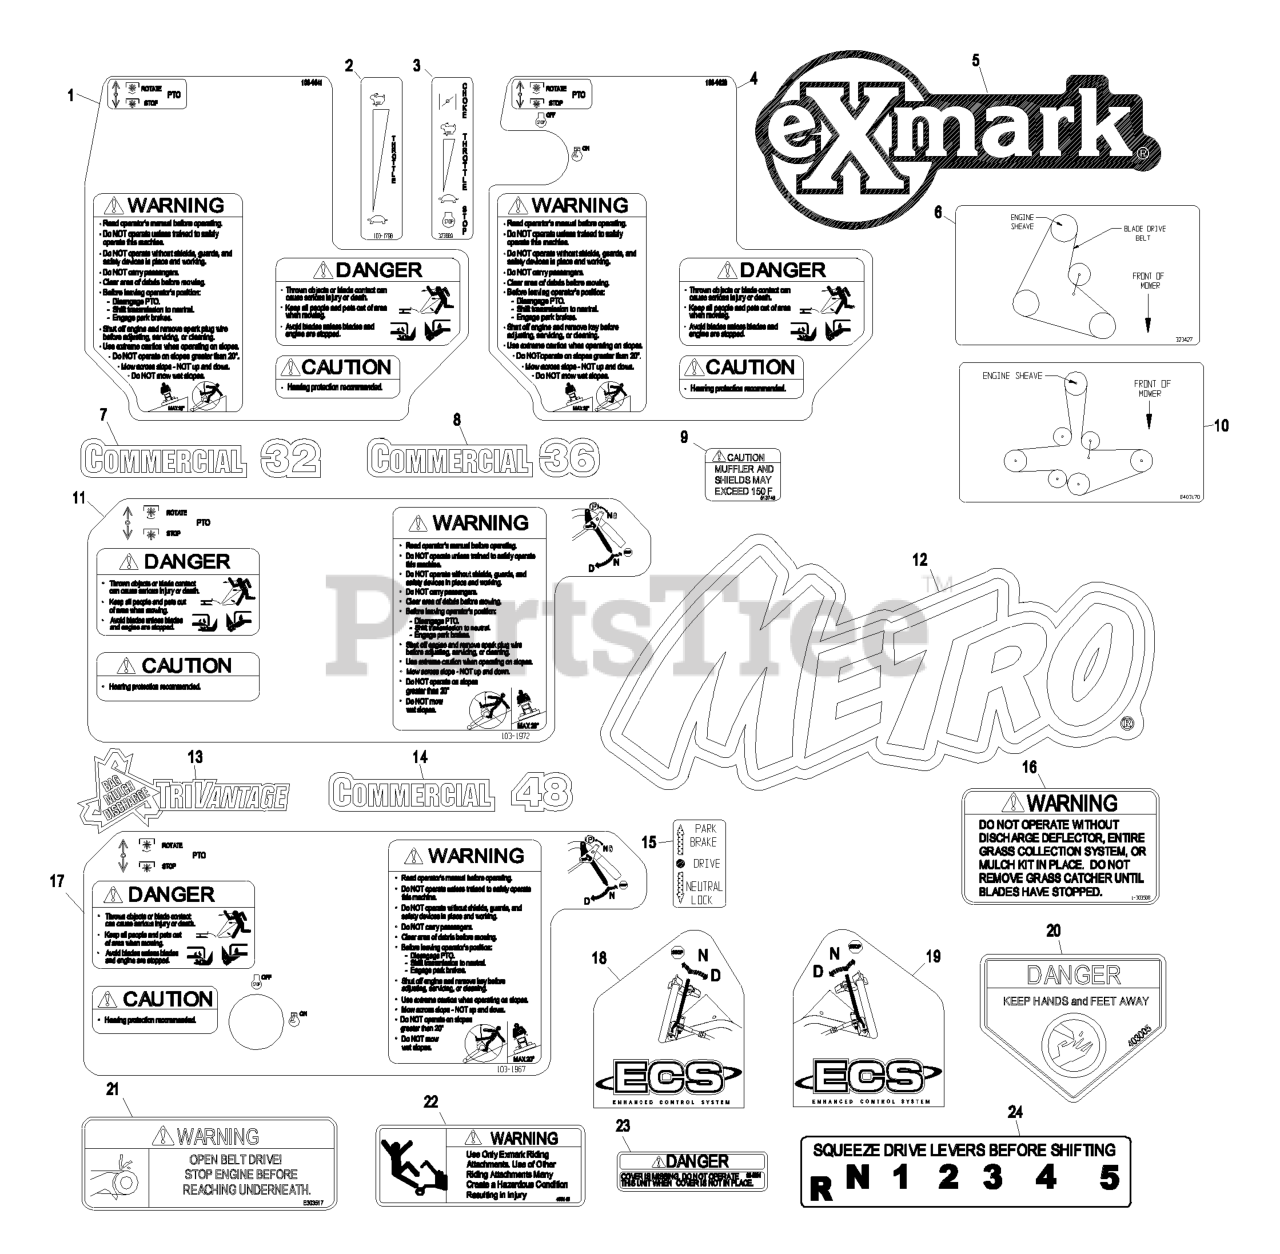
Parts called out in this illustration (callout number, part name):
1	DECAL,METRO ECS CONSOLE
2	DECAL,THROTTLE ONLY
4	DECAL,METRO ECS CONSOLE
5	DECAL,EXMARK LOGO
6	DECAL,BELT ROUTING 32/36
7	DECAL,COMMERCIAL 32
8	DECAL,COMMERCIAL 36
11	DECAL,CONSOLE
12	DECAL,METRO MODEL
14	DECAL,COMMERCIAL 48
15	DECAL,NEUTRAL/BRAKE
16	DECAL-WARNING, DISCHARGE
17	DECAL,CONSOLE
18	DECAL,RH ECS INSTRUCTION
19	DECAL,LH ECS INSTRUCTION
20	DECAL-DANGER
21	DECAL-DANGER
22	DECAL,SULKY WARNING
23	DECAL-COVER, MISSING
24	DECAL,SHIFTER
